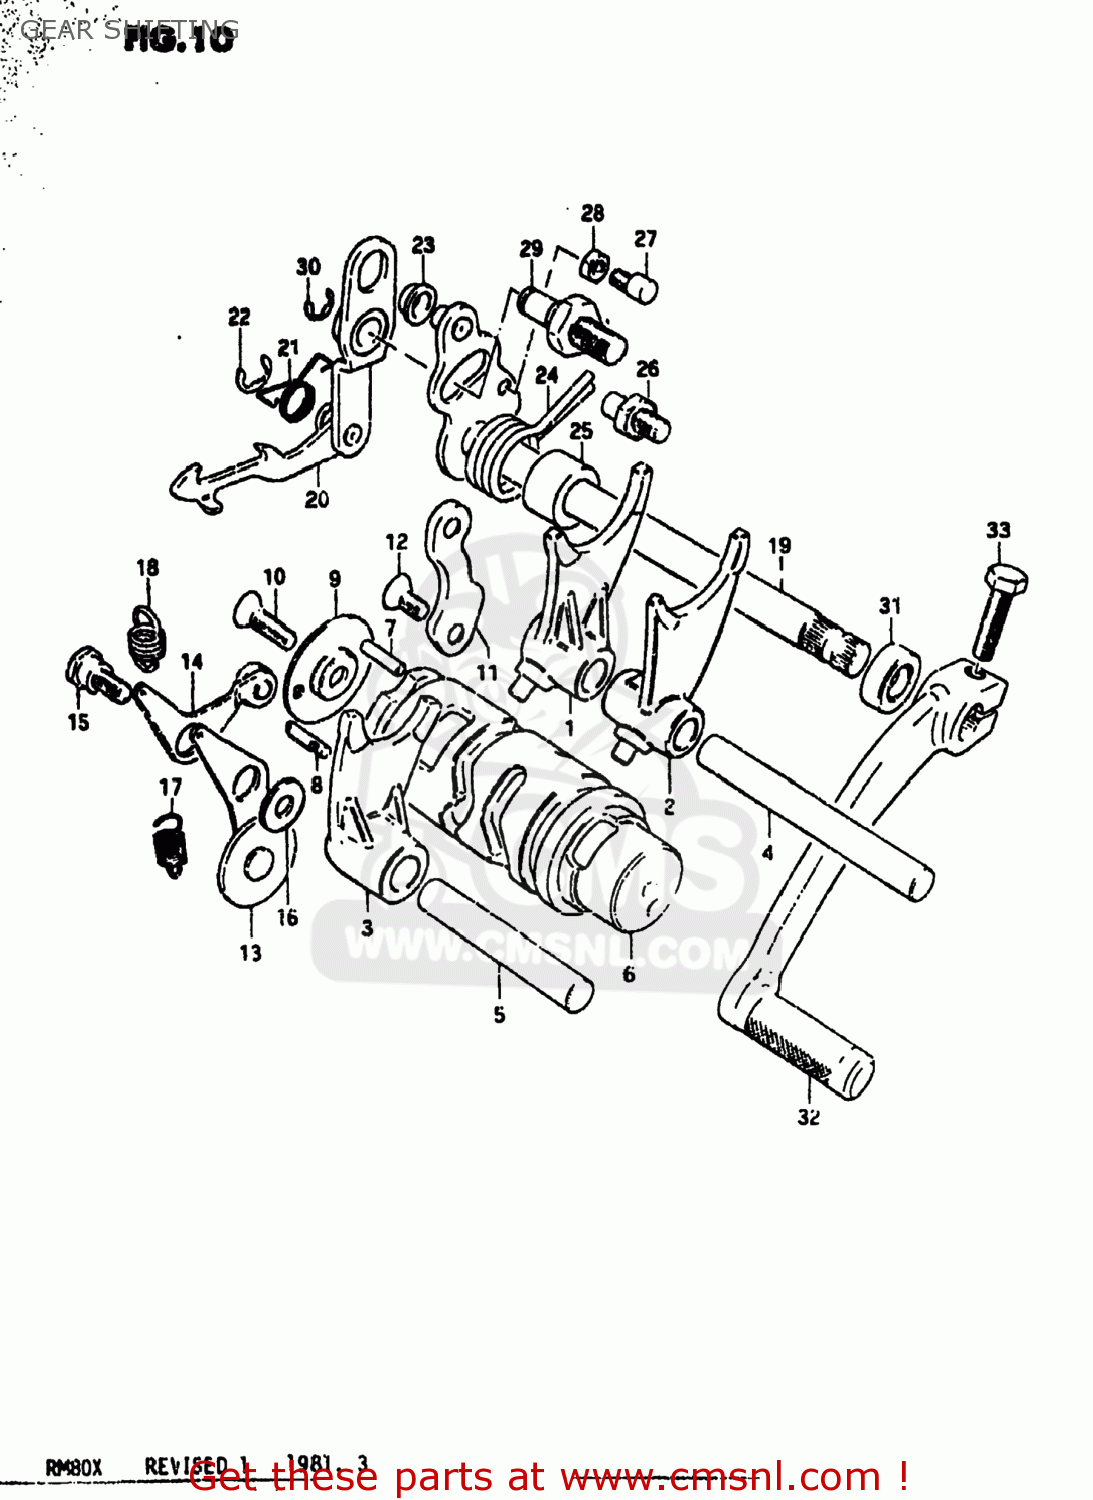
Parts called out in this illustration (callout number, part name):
1	FORK,GEAR SHIFT NO.1
2	FORK,GEAR SHIFT NO.2
3	FORK,GEAR SHIFT NO.2
4	SHAFT,GEAR SHIFT FORK
5	SHAFT,GEAR SHIFT FORK
6	CAM,GEAR SHIFT
7	PIN(4X15.8)
8	PIN
9	RETAINER,GEAR SHIFT CAM
10	SCREW
11	GUIDE,GEAR SHIFTING CABLE
12	SCREW
13	STOPPER,SHIFT CAM
14	STOPPER,GEAR SHIFT CAM
15	BOLT(6X18.3)
16	WASHER (6.5X13X2.3)
17	SPRING
18	SPRING
19	SHAFT,GEAR SHIFT
20	PAWL,GEAR SHIFT
21	SPRING
22	E RING
23	SPACER(7X10X5)
24	SPRING
25	SPACER(12X20X15.3)
26	STOPPER,GEAR SHIFT CAM
27	BOLT,GEAR SHAFT RETURN SPR SET
28	NUT 6MM
29	STOPPER,GEAR SHIFT CAM
30	E RING 6MM
31	OIL SEAL
32	LEVER ASSEMBLY,GEAR SHIFTING
33	BOLT
